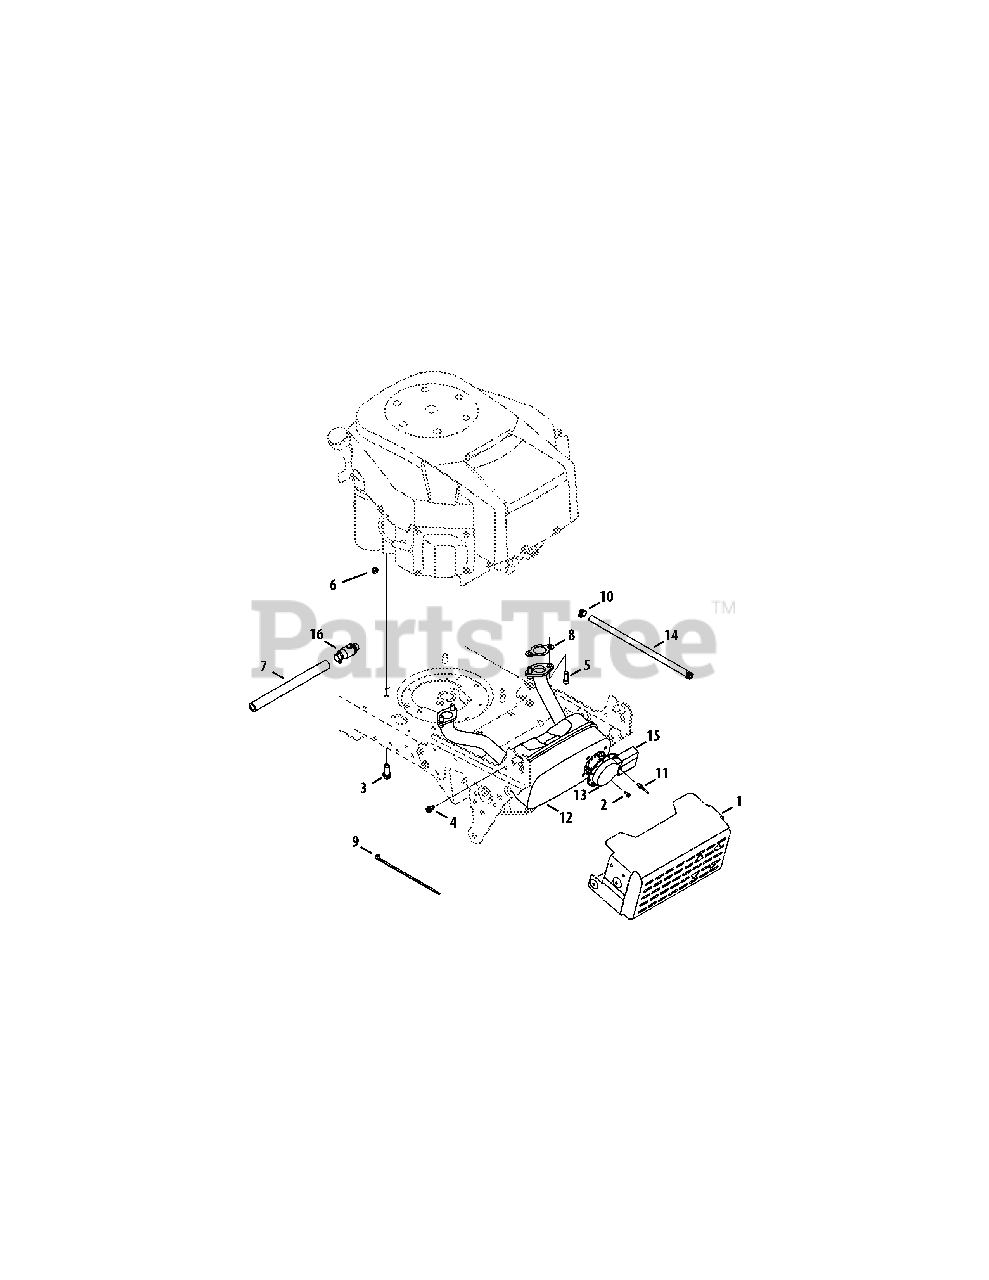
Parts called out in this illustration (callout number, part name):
1	Shield Ass’y, Muffler
2	Screw, Ab, #8-18, 0.500,
3	Screw, Self-tapping, 3/8-16, 1.000,
4	Screw, Self-tapping, 1/4-20, 0.500,
5	Screw, Socket Head, 5/16-18, .750
6	Nut, Sems, 1/4-20
7	Hose, Extension, Oil Drain
8	Gasket, Exhaust
9	Cable, Tie, 3/16 x .05 x 7.4
10	Clamp, Hose, .490 Dia.
11	Rivet, Pop, .188 Dia x .300
12	Muffler, Kohler Twin
13	Deflector, Muffler
14	Hose, Fuel, Low Permeation, 1/4
15	Deflector, Muffler, Long
17	Hose, Vent
